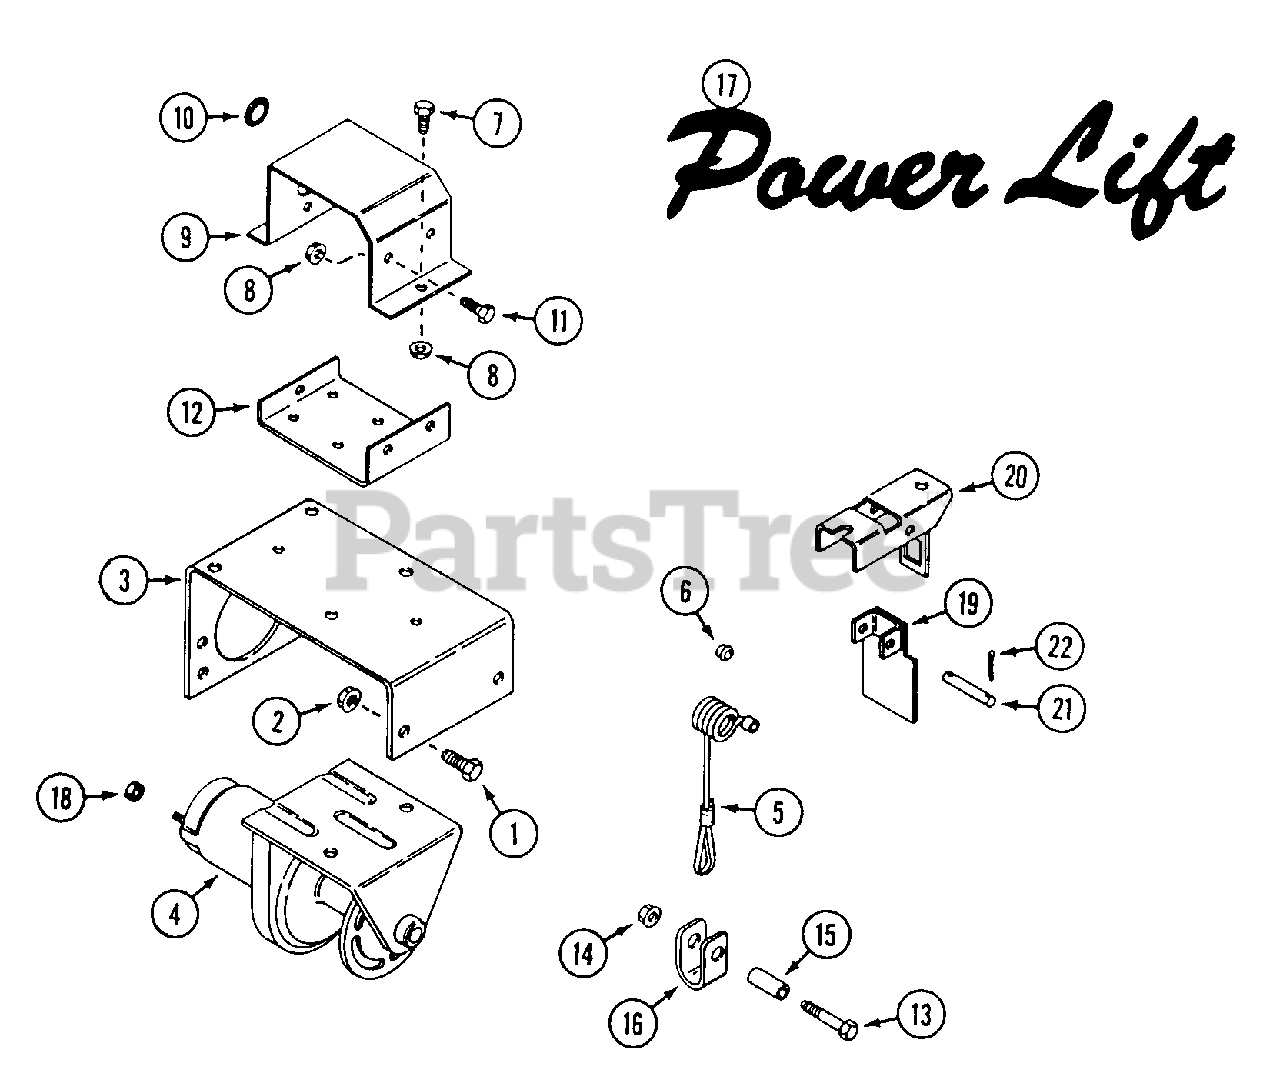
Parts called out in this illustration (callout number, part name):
1	BOLT - 3/8" - 16 x 1"
2	NUT - 3/8" - 16 flange lock
3	MOUNT - winch
4	WINCH - deck lift
6	PIN - cable keeper
7	BOLT - 1/4" - 20 x 3/4"
8	NUT - 1/4" - 20 flange lock
9	COVER - solenoid
10	GROMMET - 1" x 7/8"
11	BOLT - 1/4" - 20 x 1/2"
12	MOUNT - solenoid
13	BOLT - 3/8" - 16 x 2"
14	NUT - 3/8" - 16 lock
17	DECAL - "Power Lift"
18	NUT - #10 - 32
20	MOUNT - trip arm
22	PIN - cotter 1/16" x 5/8"
